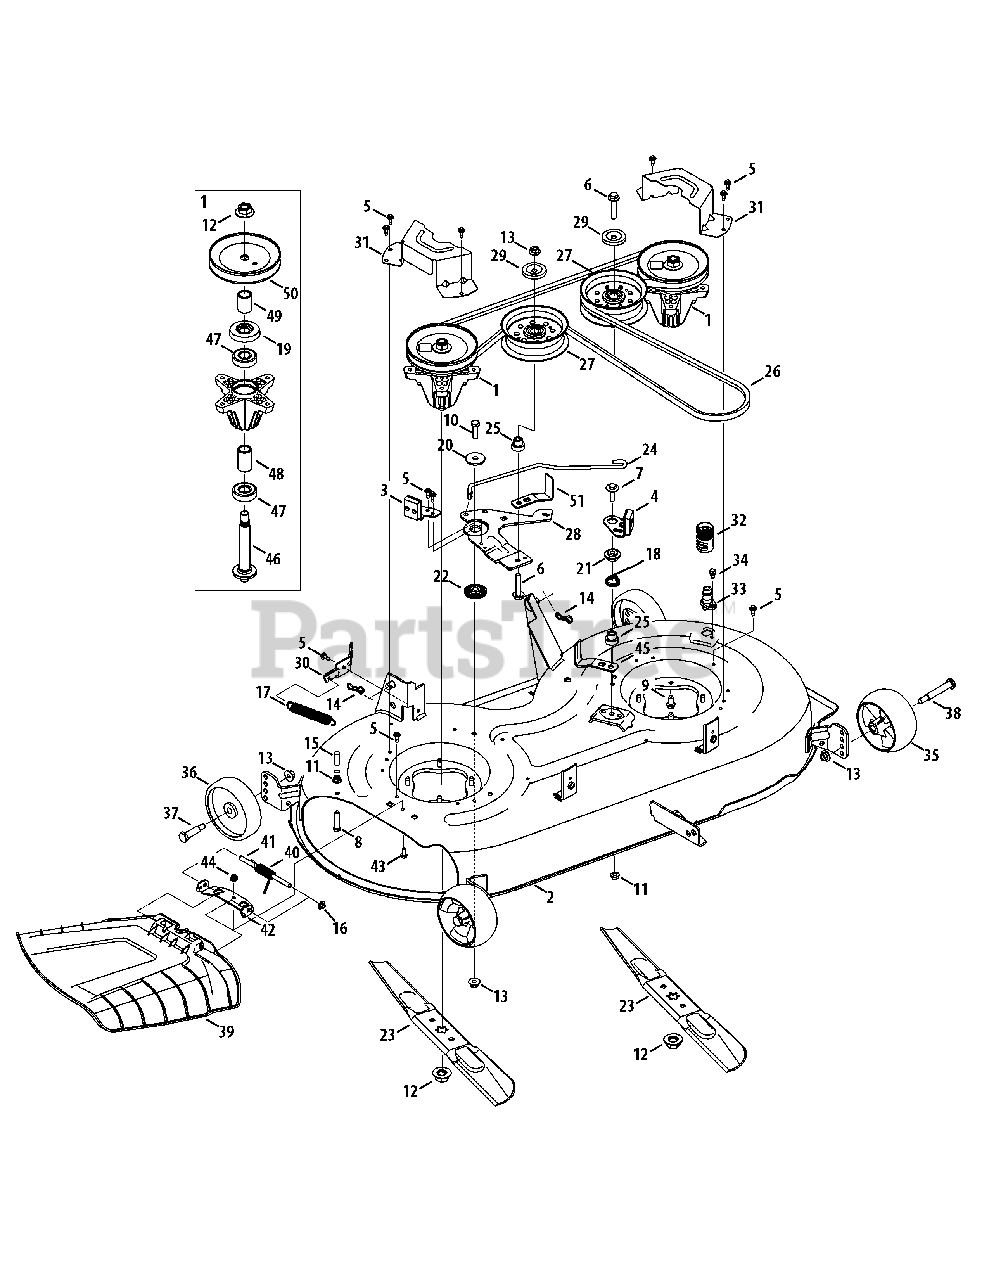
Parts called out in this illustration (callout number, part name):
1	Spindle Ass’y, Pulley, 6.3 Dia
2	Deck, 42"
3	Brake Assembly, Deck, RH
4	Brake Assembly, Deck, LH
5	Screw, M6-1 x .625
6	Hex Cap Screw, 3/8-16 x 2.00
7	Hex Cap Screw, 5/16-18 x 1.25
8	Hex Cap Screw, 5/16-18 x 1.00
9	Screw, Self-tapping, 5/16-18, 0.750,
10	Hex Cap Screw, 3/8-16 x 1.25
11	Nut, Flange Lock, 5/16-18, Nylon
12	Nut, Flange, 5/8-18
13	Flange Lock Nut, 3/8-16
14	Bow-Tie Cotter Pin
15	Vinyl Cap, .29 x .50
16	Push Cap
17	Spring, Extension, .750 x .477
18	Spring, Torsion, LH Brake
19	Bearing Shield
20	Flat Washer, .39 x 1.5 x .134
21	Shoulder Spacer, .75 x .145
22	Shoulder Spacer, .854 x .191
23	Blade, Cut, 21.23" 2-In-1, Cub
24	Rod, Brake, Deck
25	Shoulder Spacer, Idler
26	Belt, V-Type, A Sec x 99.75
27	Pulley, Idler, 4.50" Dia.
28	Idler Bracket
29	Pulley Cap
30	Bracket, Cable, PTO
31	Belt Cover
32	Coupler, Water
33	Deck Wash Nozzle
34	Shoulder Screw, 1/4-20 x 0.50
35	Wheel, Deck, 5.0 Dia. Ball
36	Wheel, Deck 5.0 x 1.38
37	Bolt, Shoulder, .496 x 1.525, 3/8-16
38	Bolt, Shoulder, .496 x 2.50, 3/8-16
39	Chute Deflector Assembly
40	Spring, Torsion, .440 ID x 1.75
41	Hinge Pin
43	Hex Cap Screw, 1/4-20 x .62
44	Nut, Flange Lock, 1/4-20, Nylon
45	Belt Keeper
46	Shaft, Spindle, 5.75
47	Bearing, Ball, .787id x 1.85 Od x .551
48	Spacer, .792 x 1.060 x 1.860
49	Spacer, .800 x 1.10 x 1.470
50	Pulley, Deck, 5.40 Dia.
